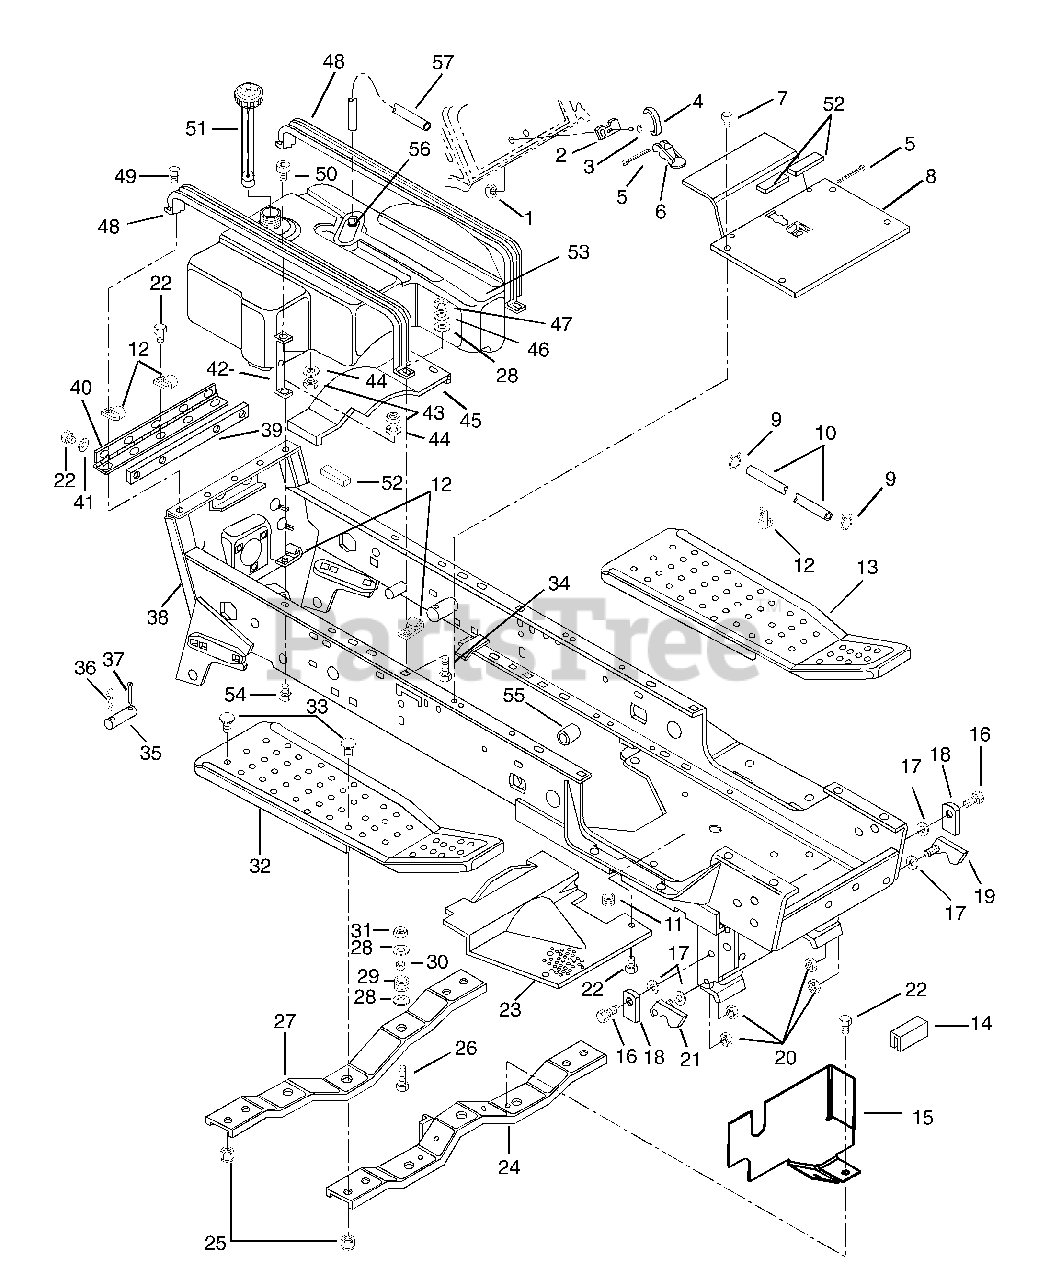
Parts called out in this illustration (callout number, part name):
1	NUT-LK-DUAL FACE 10-24 YWZC
3	SCR-MCH 10-24X.50 SLRH YWZC
4	SPRING - DECK LATCH
5	@PIN-CTR .12X1.25 EXTPRSQCT YZ
6	LEVER - DECK LATCH
7	@SCR-TAP .25-20X.37 HWH YWZ TR
8	PLATE - FLOOR
9	CLAMP-HOSE WIR.490/.510X.092#8
10	FUEL LINE 1/4 X 67"
11	HOLE PLUG 1.375
12	J-CLAMP
13	L.H. RUNNING BOARD
16	@BLT-HEX .38-16X1.00 GR5 YWZC
17	SPRING WASHER
18	LOCK STOP
19	LATCH LH
20	@NUT-LK-CTR .38-16 YWZC
21	LATCH RH
22	@SCR-TAP .31-18X.50 HWH TR YWZ
24	FRONT CHANNEL
25	@NUT-SPNLK-FLG .312-18 YWZC
26	@BLT-HEX .31-18X1.25 GR5 YWZC
27	REAR CHANNEL
28	@WSHR-FL-STL.38X.875X.083 YWZC
29	GROMMET .438ID X .688 OD
30	SPACER .318X.430X.375
31	@NUT-LK-CTR .31-18 YWZC
32	R.H. RUNNING BOARD
33	BLT-RDHDSQNK .31-18X.75 PL BL
34	BLT-RDHDSQSHK.31-18X.75 GR2 YW
36	PIN-HAIR-INT .15X.43X2.75 YWZC
37	@PIN-CTR .12X1.00 EXTPRSQCT YZ
38	FRAME, MAIN
40	HINGE-2" X 12.88 YWZC
41	@WSHR-FL-STL.38X.875X.083 YWZC
42	SUPPORT
43	@NUT-HEX .25-20 YWZC
44	WSHR-LK .250X.077 HVY YWZC
46	WSHR-LK .312X.097 HVY YWZC
47	@NUT-HEX .31-18 YWZC
48	CHANNEL
49	@SCR-TAP .31-18X.75 HWH TR YWZ
50	SCR-SKH .25-20X.75 TSPH PL
51	GAS GAUGE & CAP
52	FOAM TAPE
53	GAS TANK ASSEMBLY
54	@BLT-RDHDSQNK .25-20X.75 G5YZ
55	BSHG-SLV .750X.814X .750 BRZ
56	FITTING - GAS TANK
57	GAS TANK FUEL LINE
